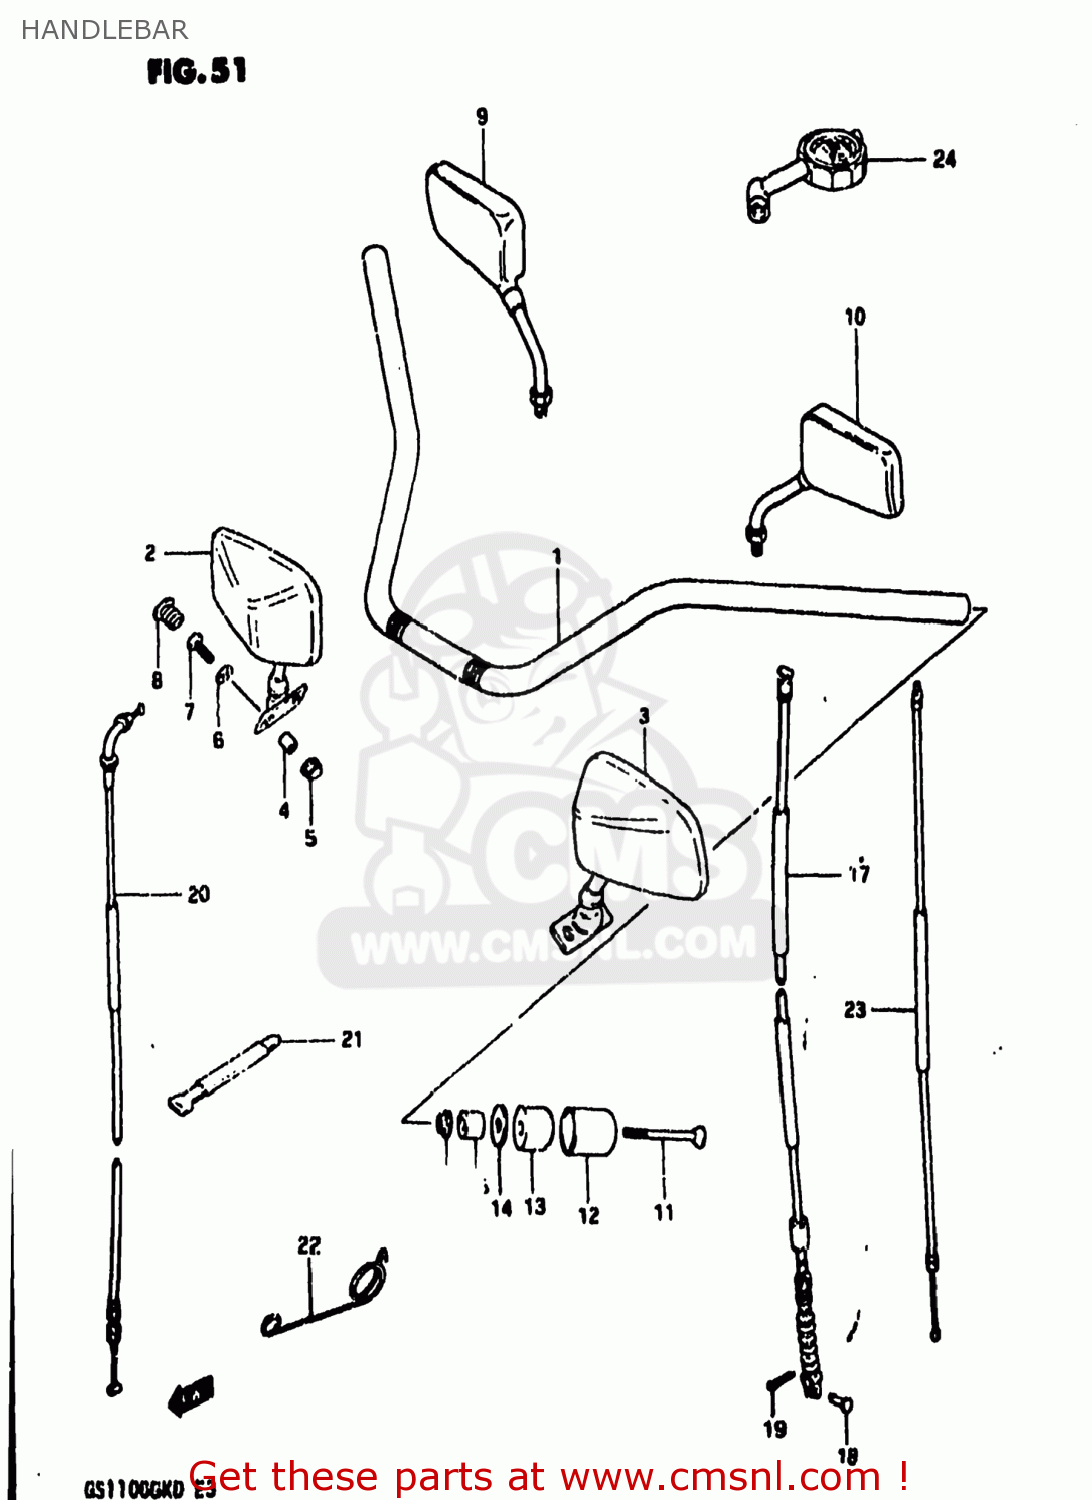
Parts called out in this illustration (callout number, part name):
1	HANDLEBAR
2	MIRROR ASSEMBLY,RIGHT
3	MIRROR ASSEMBLY,LEFT
4	SPACER(6.3X9.3X16.5)
5	NUT
6	WASHER
7	SCREW
8	CAP(OD:14)
9	MIRROR ASSEMBLY,REAR VIEW
10	MIRROR ASSEMBLY,REAR VIEW
11	SCREW
12	CAP,BALANCER
13	BALANCER,HANDLE
14	SPACER,BALANCER
15	EXPANDER,HANDLE BALANCER
16	SCREW
17	CABLE ASSY,CLUTCH
18	PIN(L:15)
19	PIN
20	CABLE ASSEMBLY,THROTTLE
21	CLAMP
22	GUIDE,CLUTCH CABLE
23	CABLE ASSEMBLY,STARTER
24	GAUGE ASSY,AIR PRESSURE
